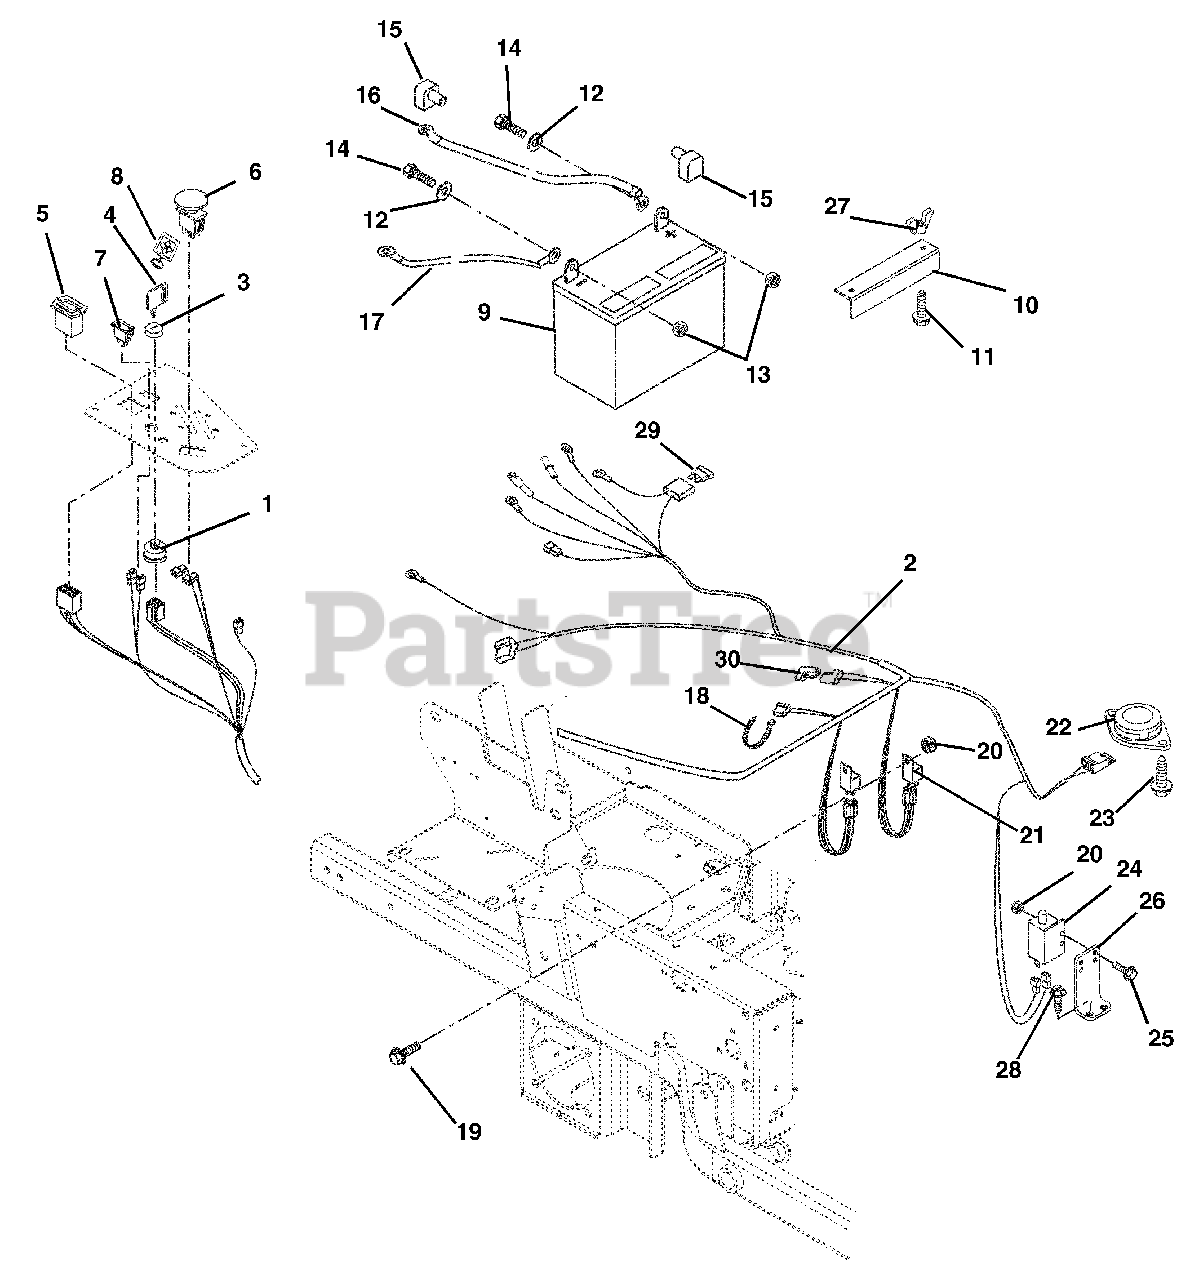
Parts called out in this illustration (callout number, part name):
1	Key Switch
2	Harness, Z 6-Pin Wiring
3	Cap-Ignition Switch
4	Key with Shield
5	Hour Meter
6	Switch-Clutch With Retainer Ring
7	Light-Indicator Kit
8	Key Chain
10	Hold Down
11	Bolt, Round Head Square Neck .25-20 x 7.50
12	Washer-Flat-Steel .281 x .620 x .065
13	Nut-Locking-Top-Flange .25-20
14	Bolt-Hex .25-20 x .75 Grade 5
15	Insulator
16	Positive Cable 22"
17	Ground Cable
18	Cable Tie
19	Screw-Machine 10-24 x .50 Hex Washer Head
20	Nut-Locking-Nylon 10-24 With Insert
21	Relay
22	Seat Switch
23	Screw-Tapping 12-24 x .50 Hex Washer Head
24	Switch-Single Pole
25	Screw-Machine 10-24 x .75 Hex Washer Head
26	Mount, Brake Switch
27	Nut-Locking Wing .25-20
28	Screw-Tapping .25-20 x .50 Hex Washer Head
29	Fuse, 30 Amp
30	Molded Diode Plug-Black 1-Amp
